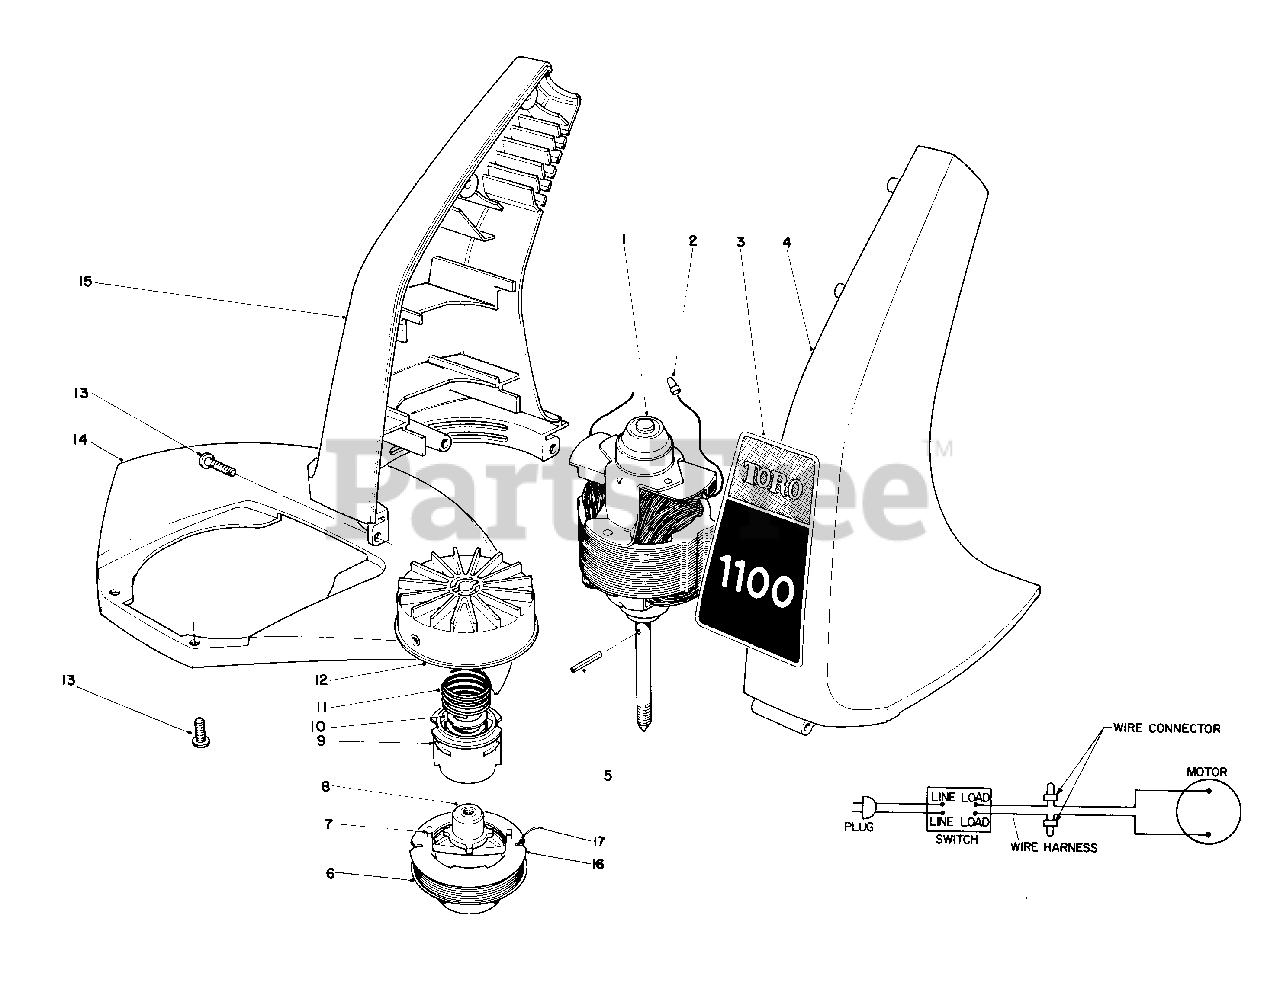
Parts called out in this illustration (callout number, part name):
2	Wire Connectors
3	1100 Decal
4	Housing-Left Hand
6	50', .065 Dia. Cutting Line Prewound on Spool
7	Saddle Clip
12	Drum With Eyelet
13	Screw
14	Shield
15	Housing-Right Hand
16	Empty Spool
17	50' Coil-.065" Cutting Line In Coil
